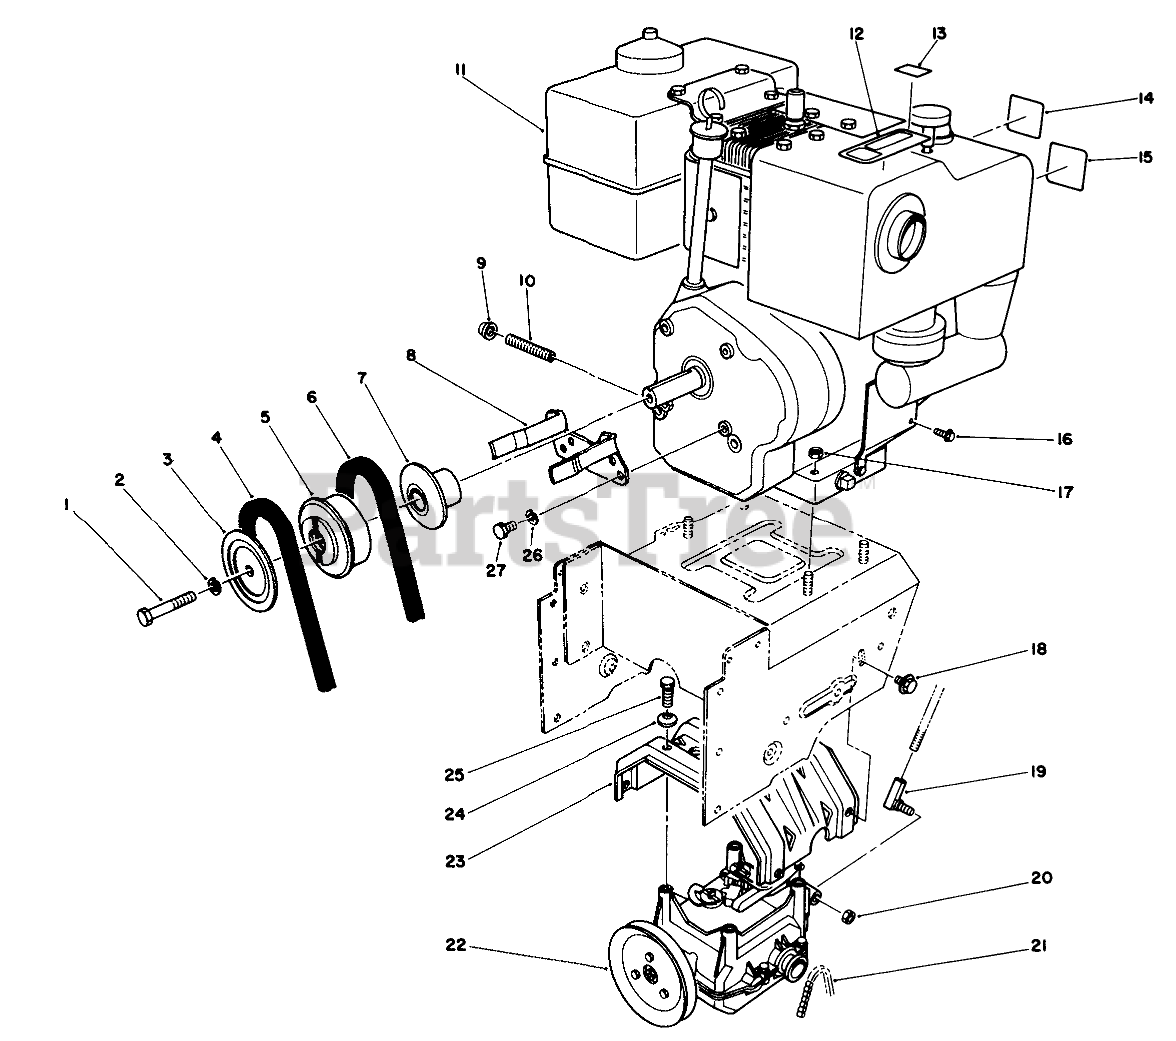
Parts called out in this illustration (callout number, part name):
1	SCREW-HH
2	WASHER-LOCK
3	SHEAVE-HALF, IMPELLER
4	V-BELT, IMPELLER
5	PULLEY-ENGINE, CENTER
6	V-BELT, TRACTION
7	SHEAVE-HALF, TRACTION
8	Guide-Belt
9	CAP-PIPE
10	NIPPLE-PIPE
12	Decal-Hot
13	DECAL - CHOKE
14	DECAL - PRIMER, INT'L
15	DECAL - THROTTLE, INT'L
16	SCREW-HH
17	NUT-HF
18	SCREW-HHF
19	JOINT-BALL
20	NUT-LOCK
21	CHAIN
22	Transmission Assembly
23	Frame-Transmission
24	WASHER-SPRING
25	SCREW-HWHTF
26	WASHER-LOCK
27	SCREW-HH
